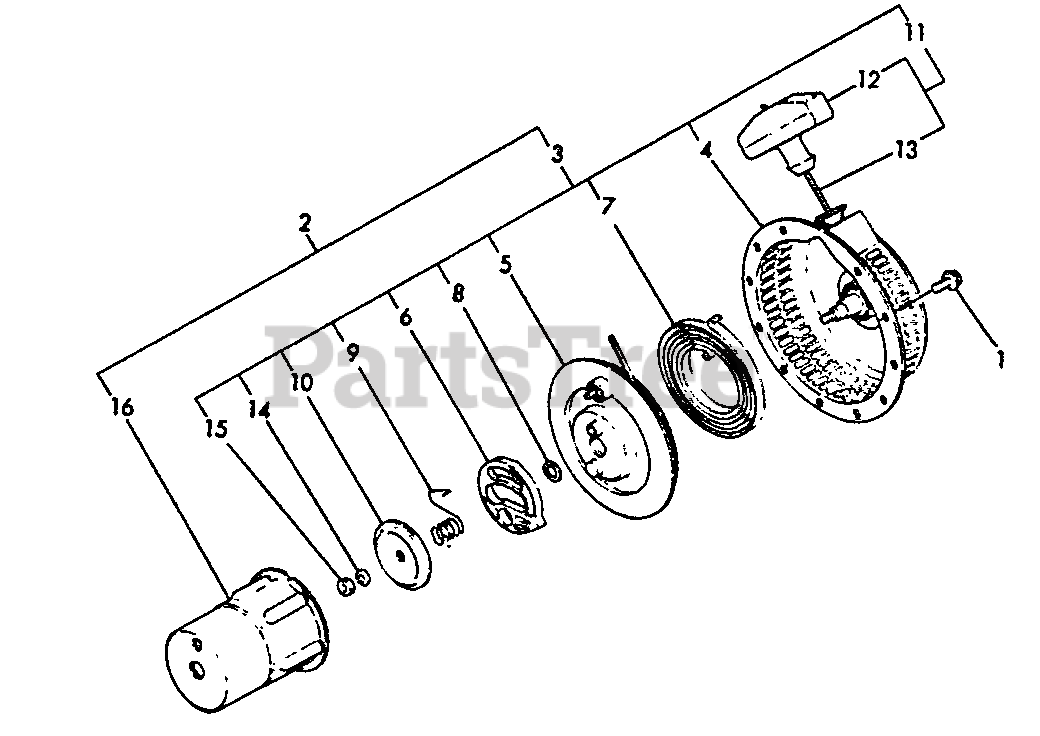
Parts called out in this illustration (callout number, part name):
1	BOLT - 6X8 -- PLATED
2	STARTER ASSY
3	STARTER ASSY
4	CASE, STARTER
5	PULLEY
8	WASHER, THRUST
9	SPRING, FRICTION
10	PLATE, FRICTION
11	STARTER ROPE ASSY
12	GRIP, STARTER
13	ROPE, STARTER
14	LOCKWASHER - 6
15	NUT - 6
16	PULLEY, STARTER
